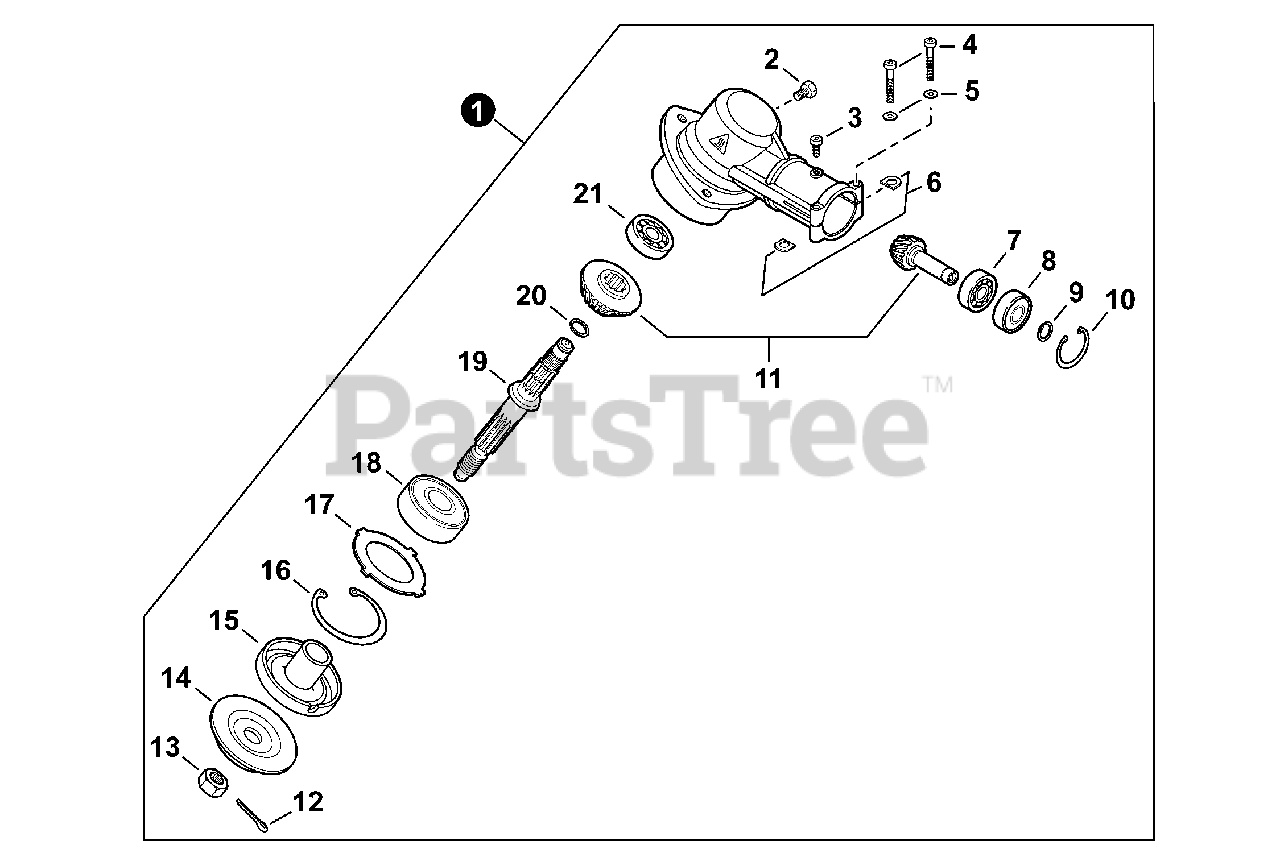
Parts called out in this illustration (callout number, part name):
1	GEAR CASE ASSY
2	BOLT M8×8
3	BOLT, TORX 5×10
4	BOLT, TORX 5×35
5	WASHER, FLAT 5.5×10×0.8
7	BEARING, BALL 6900
8	BEARING, BALL 6900Z
9	RING, SNAP Ø10
10	RING, SNAP Ø22
11	GEAR SET
12	PIN, COTTER 2×22
14	PLATE, ADAPTOR - LOWER
15	PLATE, ADAPTOR - UPPER
16	RING, SNAP Ø32
18	BEARING, BALL 6201
19	SHAFT, GEAR
20	RING, SNAP Ø12
21	BEARING, BALL 609
